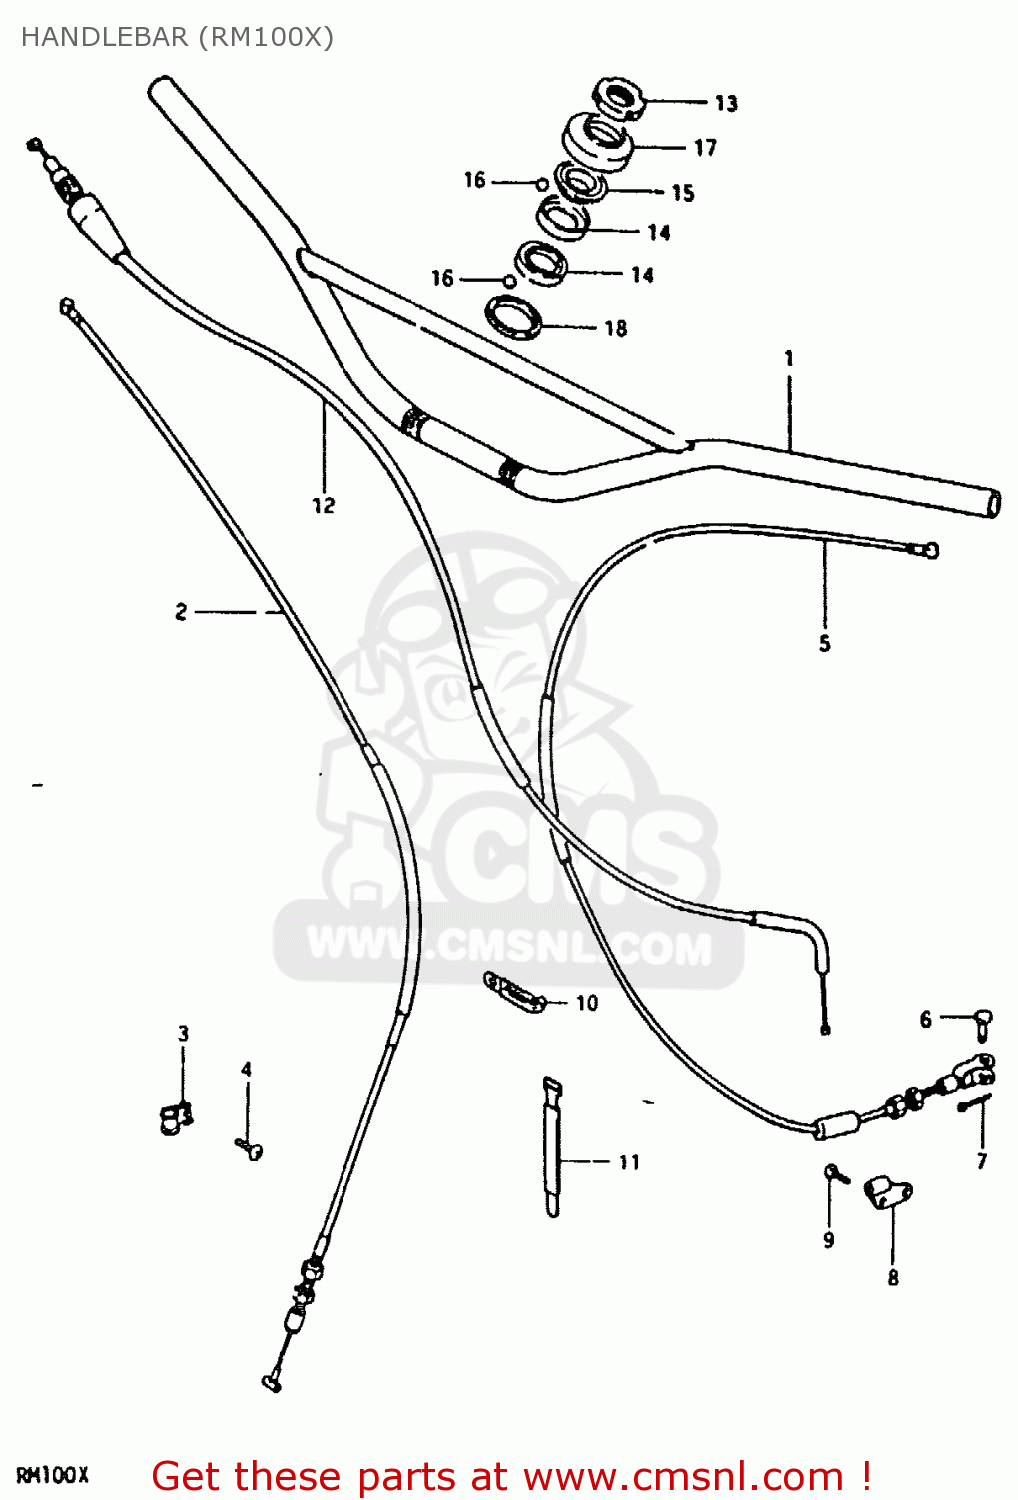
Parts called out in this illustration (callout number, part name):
1	HANDLEBAR
2	CABLE ASSEMBLY,FRONT BRAKE
3	CLIP,CABLE
4	SCREW
5	CABLE ASSY,CLUTCH
6	PIN(L:13)
7	PIN
8	STOPPER,CLUTCH CABLE
9	SCREW
10	CLAMP L:35
11	CLAMP
12	CABLE ASSEMBLY,THROTTLE
13	NUT,STEERING STEM
14	RACE,STEERING,INNER,UPPER
15	RACE,STEERING,OUTER,UPPER
16	BALL
17	SEAL,STEERING UPR DUST
18	DUST SEAL,STEERING HEAD
